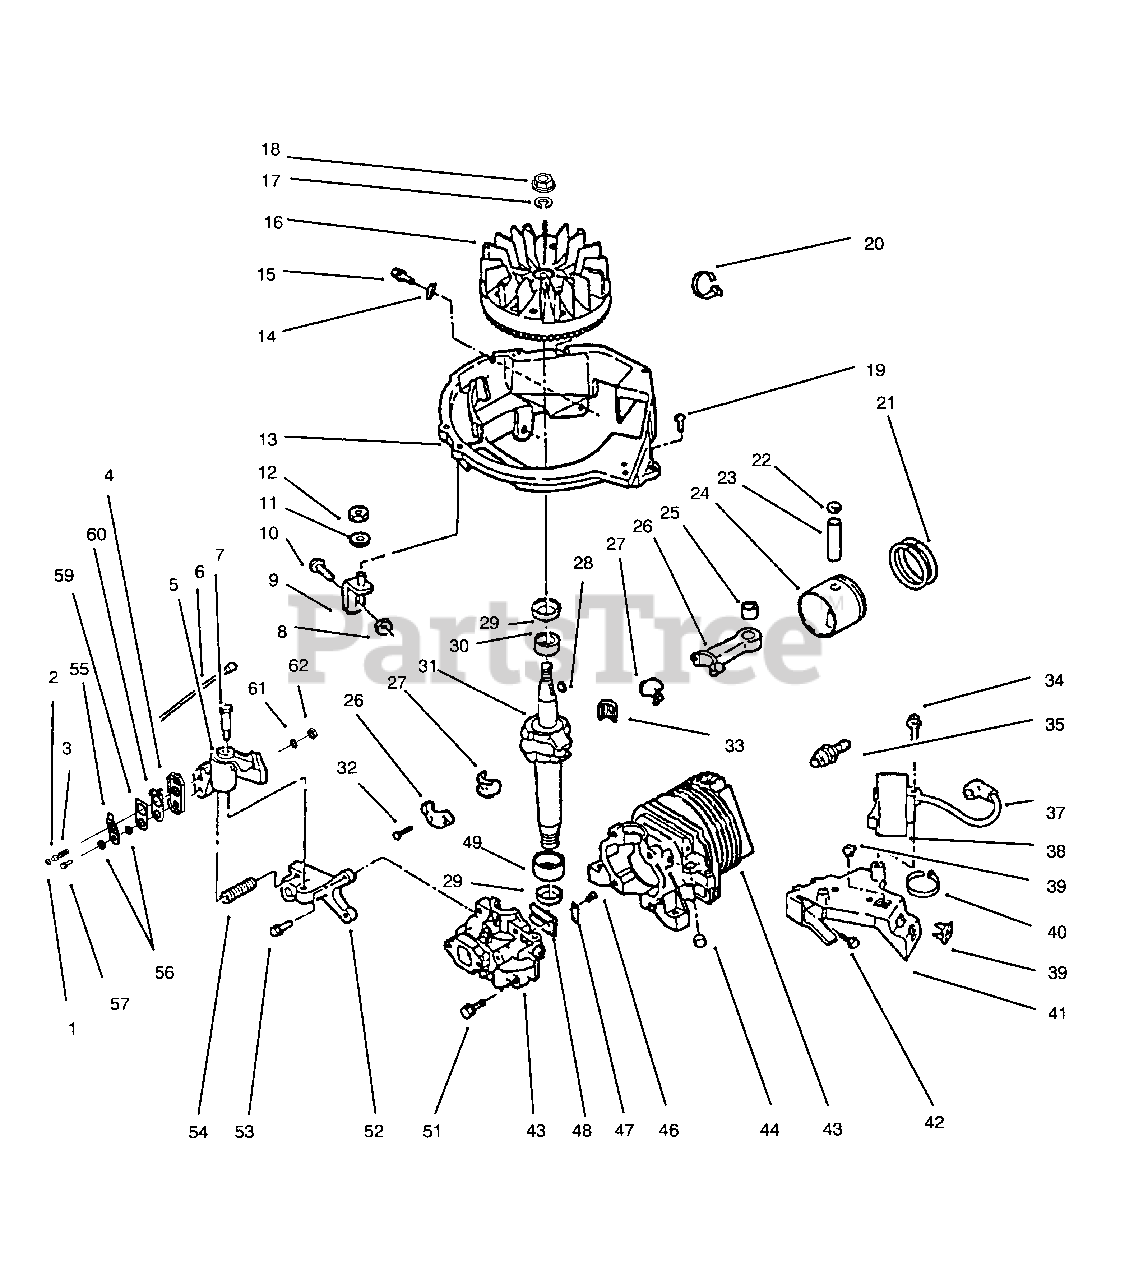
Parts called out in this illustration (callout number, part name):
1	Retainer
2	Actuator-Brake Lever
3	Spring-Cable, Return
4	Case-Switch
5	Brake Assembly
6	Wire Lead
7	Bolt-Shoulder
9	Brace Assembly
11	Washer
13	Shroud-Base
14	"J" Clip
16	Flywheel Assembly
17	Washer-Lock
18	Nut-Flywheel
20	Tie Strap
21	Set-Ring
22	Ring-Retaining
23	Pin-Wrist
24	Piston & Connecting Rod Assembly (Incl. Ref. #21-23, 25-27 & 32-33)
25	Bearing Assembly
26	Connecting Rod Assembly (Incl. Ref. #25,27,32 & 33)
27	Liner-Pair
28	Key-Flywheel
29	Seal-Oil
30	Bearing-Main
31	Crankshaft
33	Set-Needle Bearing
34	Screw
35	Spark Plug
37	Wire Lead
38	C.D. Ignition Module (Incl. Ref. #37)
39	Grommet
40	Tie Strap
41	Bracket-C.D.
43	Cylinder & Crankcase Cover Assembly (Incl. Ref. # 46-48,51 & 53)
47	Plate-Reed
49	Bearing-Main
52	Bracket-Brake
54	Spring-Brake
56	Washer
57	Screw-Hex. Hd. Cap
60	Plate-Contact
61	Washer-Lock
62	Nut
